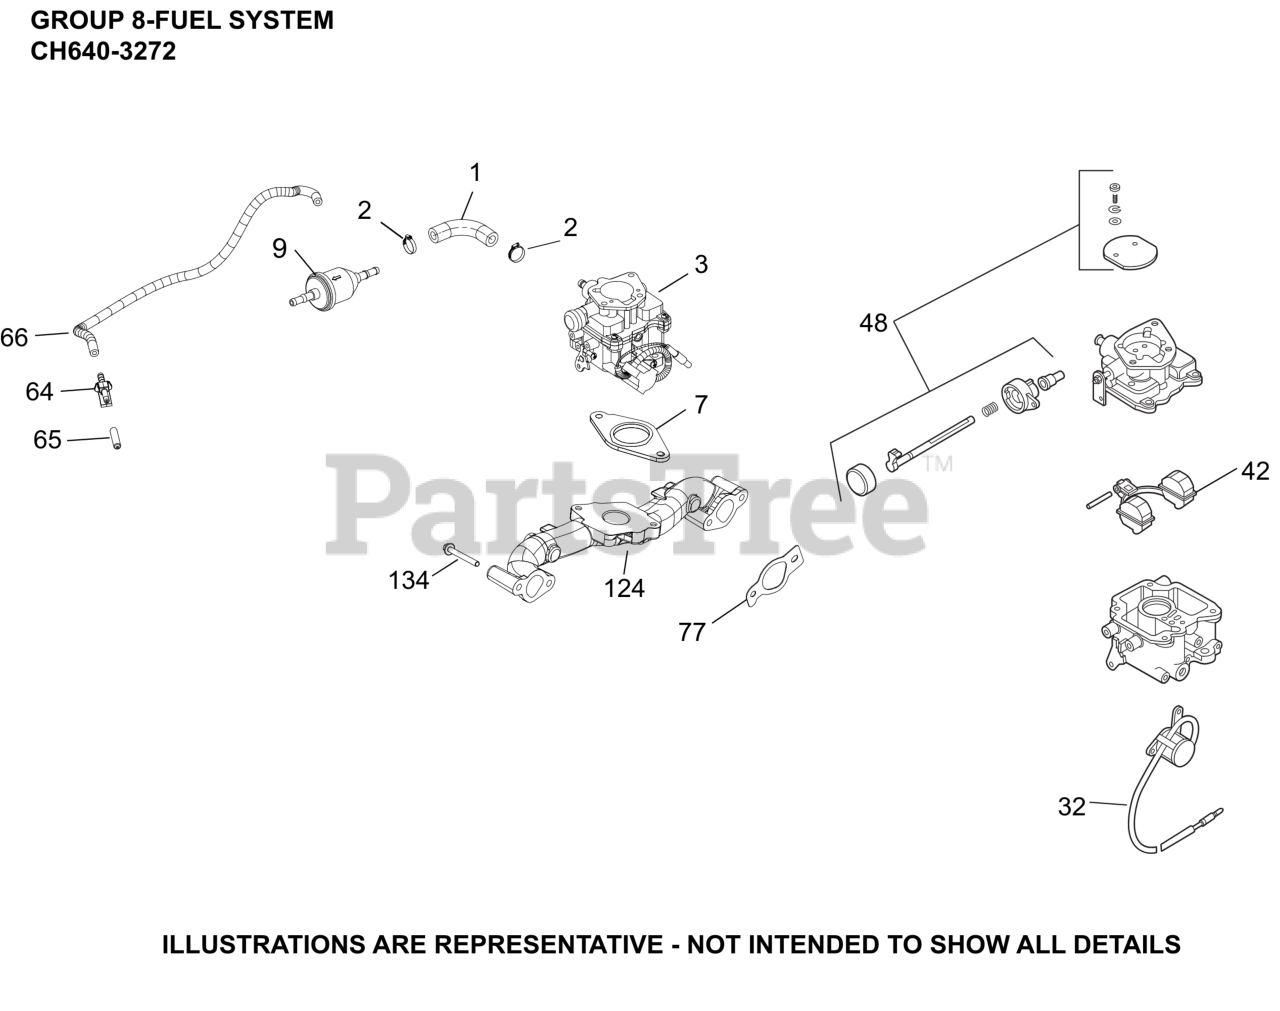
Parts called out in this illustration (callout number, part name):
1	HOSE,LW PERM.FUEL 24.00"-USE 25 111 81-S
1	HOSE, FUEL LOW PERMEATION 39"
2	CLAMP, HOSE (KM)-USE 25 237 31-S
3	KIT, CARBURETOR COMPLETE
7	GASKET, CARBURETOR
9	FILTER, FUEL
32	KIT, SOLENOID
42	KIT, REPAIR FLOAT
48	KIT, REPAIR CHOKE
64	CONNECTOR, EVAPORATIVE
65	CAP, MASKING
66	HOSE, EVAPORATIVE 20"- (#24326143S)
77	KIT, INTAKE MANIFOLD GASKET
124	MANIFOLD, METAL INTAKE
134	SCREW, HEX FLANGE
NI	KIT, HIGH ALT (4000-8000 FT)
NI	KIT, HIGH ALT (8,000+ FT)
NI	KIT, REPAIR CARBURETOR
